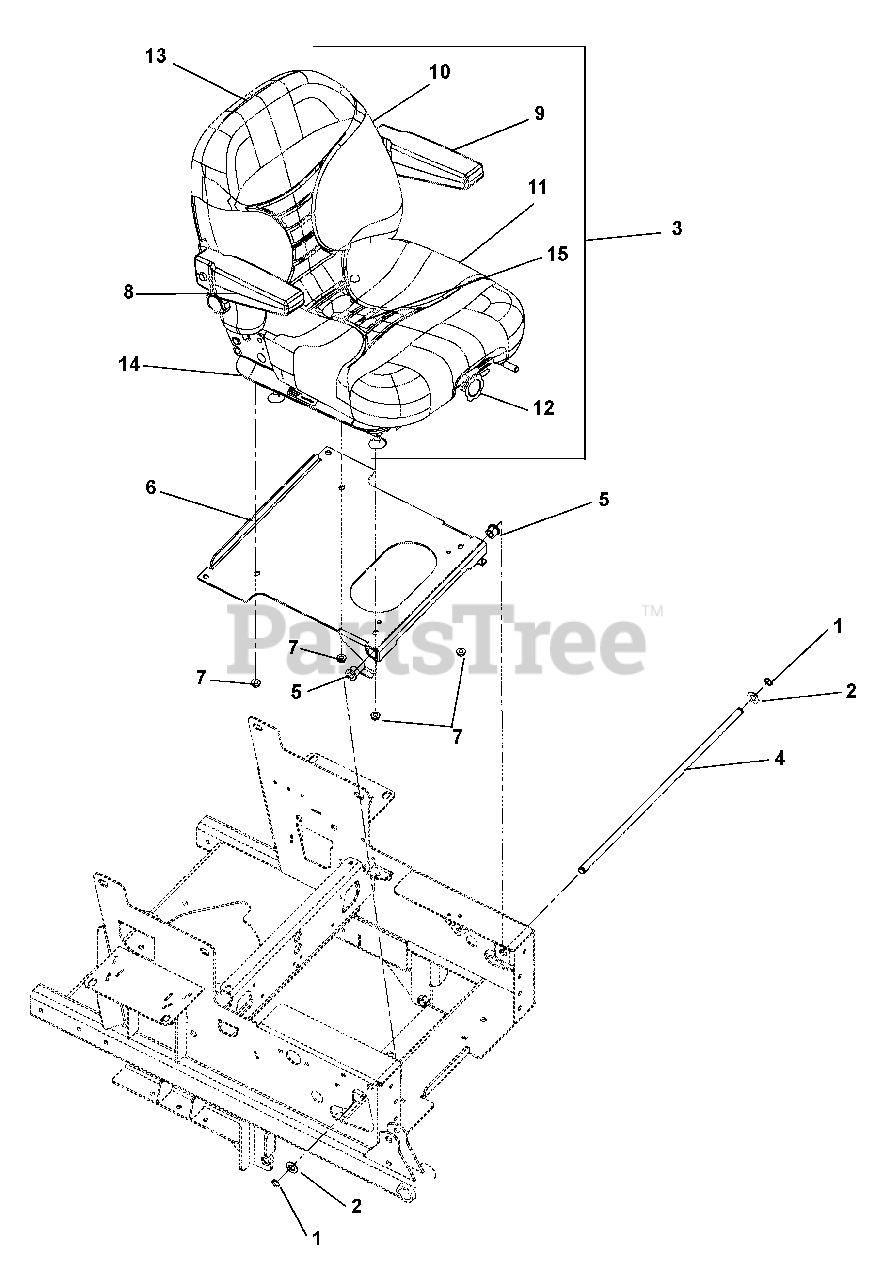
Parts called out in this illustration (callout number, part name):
1	Ring, Retaining-External .500 x .050
2	Washer, Flat Steel .531 x 1.00 x .063
3	Seat, Suspension- Light Gray
4	Shaft, 100I Seat Pivot
5	Bushing, Flange .516 x .750 x .625 x .937
6	100I Seat Plate Weldment
7	Nut, Locking-Top-Flange .31-18
8	Kit, Right Hand Armrest Assembly
9	Kit, Left Hand Armrest Assembly
10	Kit, Back Cushion, Light Grey
11	Kit, Seat Cushion, Light Grey
12	Kit, Seat Knobs
13	Kit, Seat Back
14	Kit, Seat Slides
15	Kit, Seat Spring and Saddle
